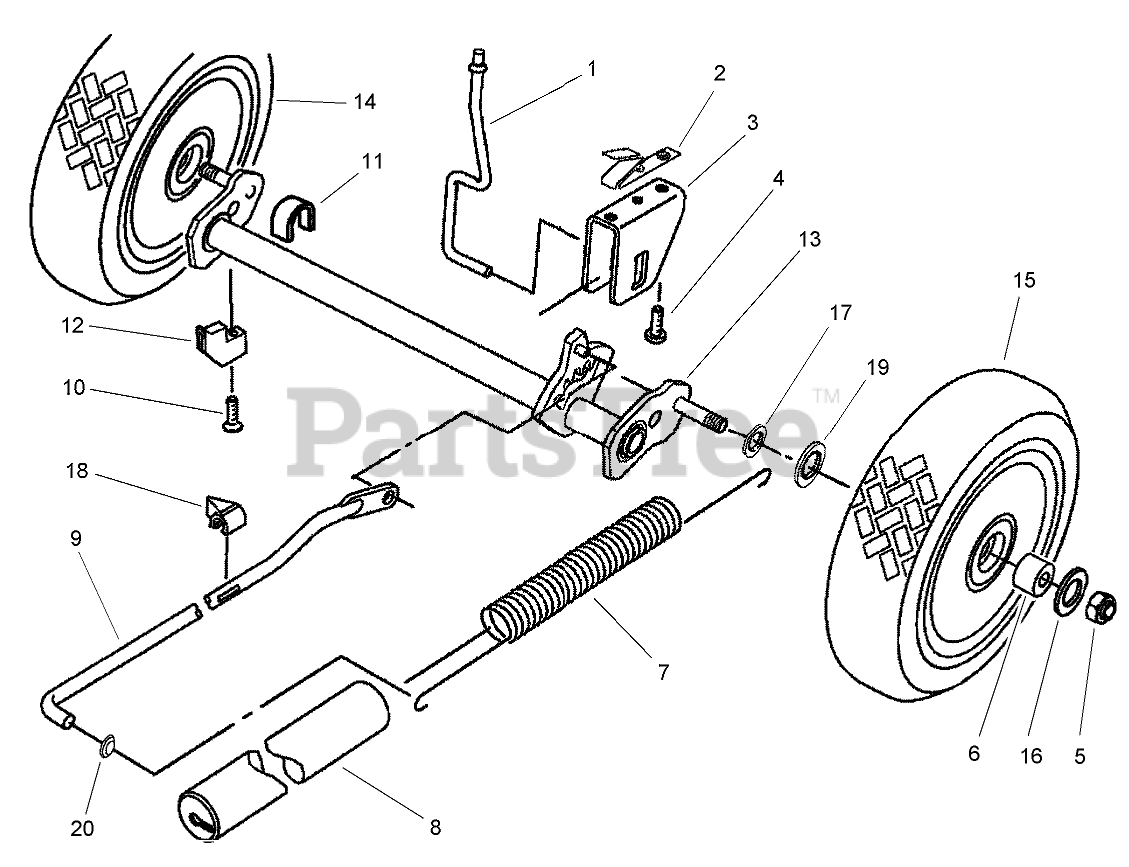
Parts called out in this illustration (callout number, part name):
1	ROD-TRIGGER
2	SPRING-RETURN, TRIGGER
3	SADDLE-HEIGHT OF CUT
4	SCREW-RH
5	NUT-HH
6	BUSHING
7	SPRING-COUNTERBALANCE
8	COVER-SPRING
9	ROD-LINK
10	SCREW-RETAINER
11	CAP-AXLE, REAR
12	RETAINER-AXLE
13	AXLE-REAR
14	WHEEL-REAR
15	WHEEL-SMART, REAR
16	WASHER-WHEEL
17	CAP-AXLE, REAR
18	INDICATOR-HEIGHT OF CUT
19	WASHER-WAVE
20	NUT-PUSH
